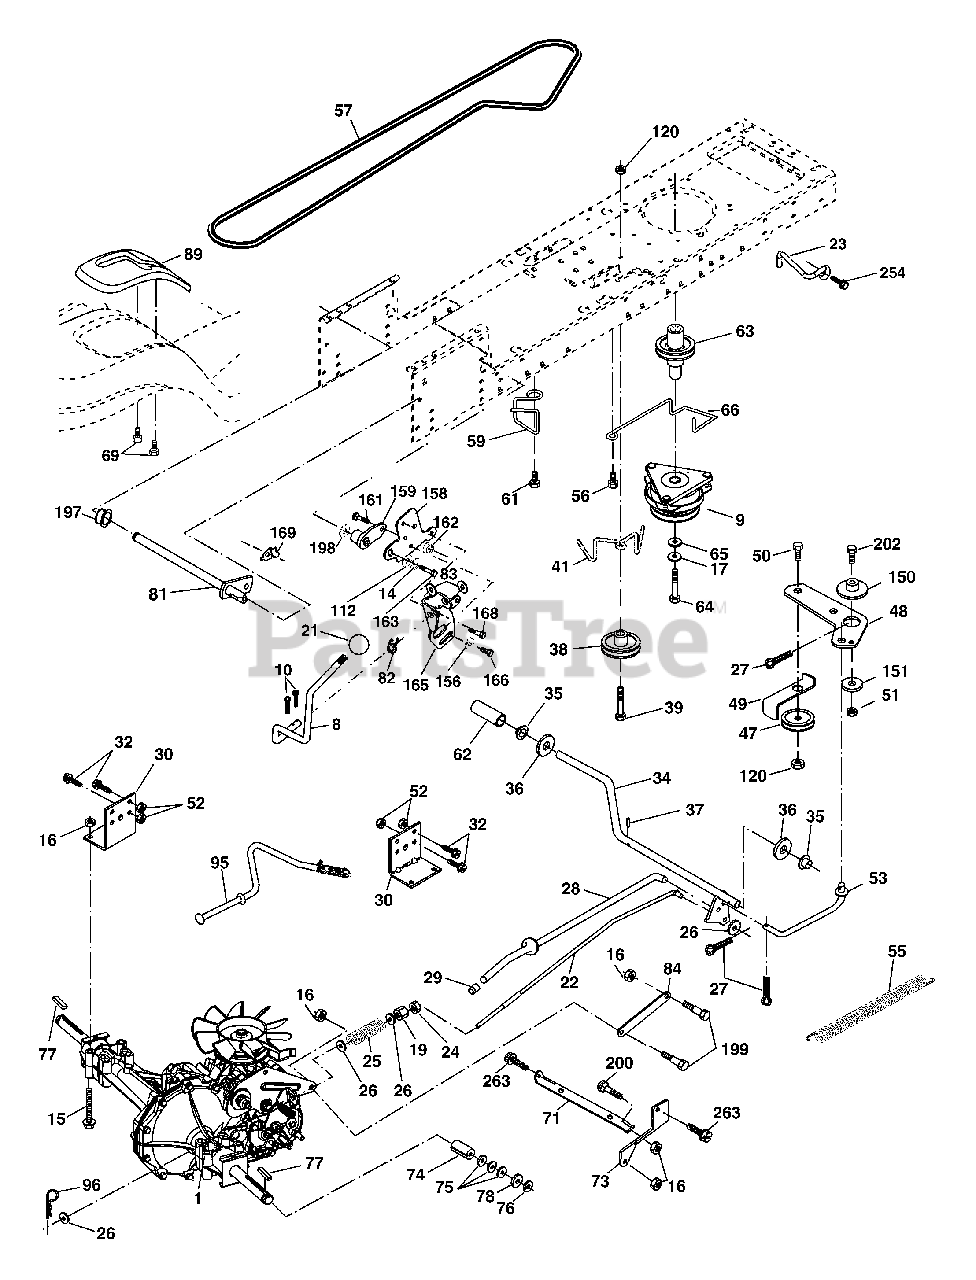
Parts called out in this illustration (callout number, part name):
8	Rod Shift
9	Clutch Ogura
10	Pin Cotter 1/8 x 1 CAD
14	Washer Lock Hvy Helical
15	Bolt, Hex FLGHD 5/16-18 Gr. 5
16	Nut Lock Hex W/Ins 5/16-18 unc
17	Washer
19	Nut Lock Hex W/Wsh 3/8-16 unc
21	Knob
22	Rod, Brake Hydro
23	Bracket Anti Rotation
24	Nut
25	Spring, Brake Rod
26	Washer
27	Pin Cotter 1/8 x 3/4 CAD.
28	Rod, Parking Brake
29	Cap, Parking Brake
30	Bracket, Transaxle
32	Bolt Hex Hd 5/16-18 unc x 3/4
34	Shaft, Foot Pedal
35	Bearing, Nylon
36	Washer
37	Pin, Roll
38	Pulley, Composite
39	Bolt Rdhd 3/8-16 unc x 2-3/4 Gr. 5
41	Keeper, Belt Idler
47	Pulley, Idler, V-Groove
48	Bellcrank Clutch Grnd Drv STL
49	Retainer, Belt
50	Bolt Carr Sh 3/8-16 x 1-1/2 Gr. 5
51	Nut Crownlock 3/8-16 unc
52	Nut Crownlock 5/16-18 unc
53	Link, Clutch
55	Spring, Return, Clutch
56	Screw
57	V-Belt, Ground Drive
59	Keeper, Center Span
61	Screw 3/8-16 x .875
62	Cover, Pedal
63	Pulley, Engine
64	Bolt Hex 7/16-20 x 4 x Gr. 5-1.5 Thr
65	Washer
66	Keeper Belt Engine
69	Screw Hex Wsh Hi-Lo 1/4 x 1/2 unc
71	Strap Torque Lh Hydro
73	Strap Torque Rh Hydro
74	Spacer, Axle
75	Washer 25/32 x 1-1/4 x 16 Ga.
76	E-Ring
77	Key, Square
78	Washer 25/32 x 1-5/8 x 16 Ga.
81	Shaft Asm. Cross Hydro
82	Spring Torsion T/A
83	Washer 17/32 x 3/4 x 16 Ga.
84	Link Transaxle
89	Console, Shift
95	Control Asm Bypass Hydro
96	Retainer Spring 1" Zinc/Cad
112	Washer 9/32 x 3/4 x 10 Ga.
120	Nut Lock Flg 3/8-16 unc
150	Spacer Retainer
151	Washer 13/32 x 2 x 10 Ga.
156	Washer Srrted 5/16 ID x 1.125
158	Bracket Shift Mount
159	Hub Shift
161	Bolt Rdhd Sqnk 1/4-20 x 3/4 Gr. 5
162	Nut Crownlock 1/4-20 unc
163	Bolt Hex Fin 1/4-20 unc x 1 Gr. 5
165	Bracket Pivot Lever
166	Screw 5/16-18 x 5/8
168	Bolt Shoulder 5/16-18 x .561
169	Plate Fastening Lt
197	Nyliner Snap-In 5/8" ID
198	Washer Nyl 7/8 ID x .105
199	Bolt Shoulder 5/16-18 unc
200	Bolt Rdhd Sqnk 5/16-18 unc x 1
202	Bolt Carr Sh 3/8-16 x 1-3/4 Gr. 5
254	Screw 3/8-16 x 1
263	Thdrol Screw 3/8-16 x 3/4
